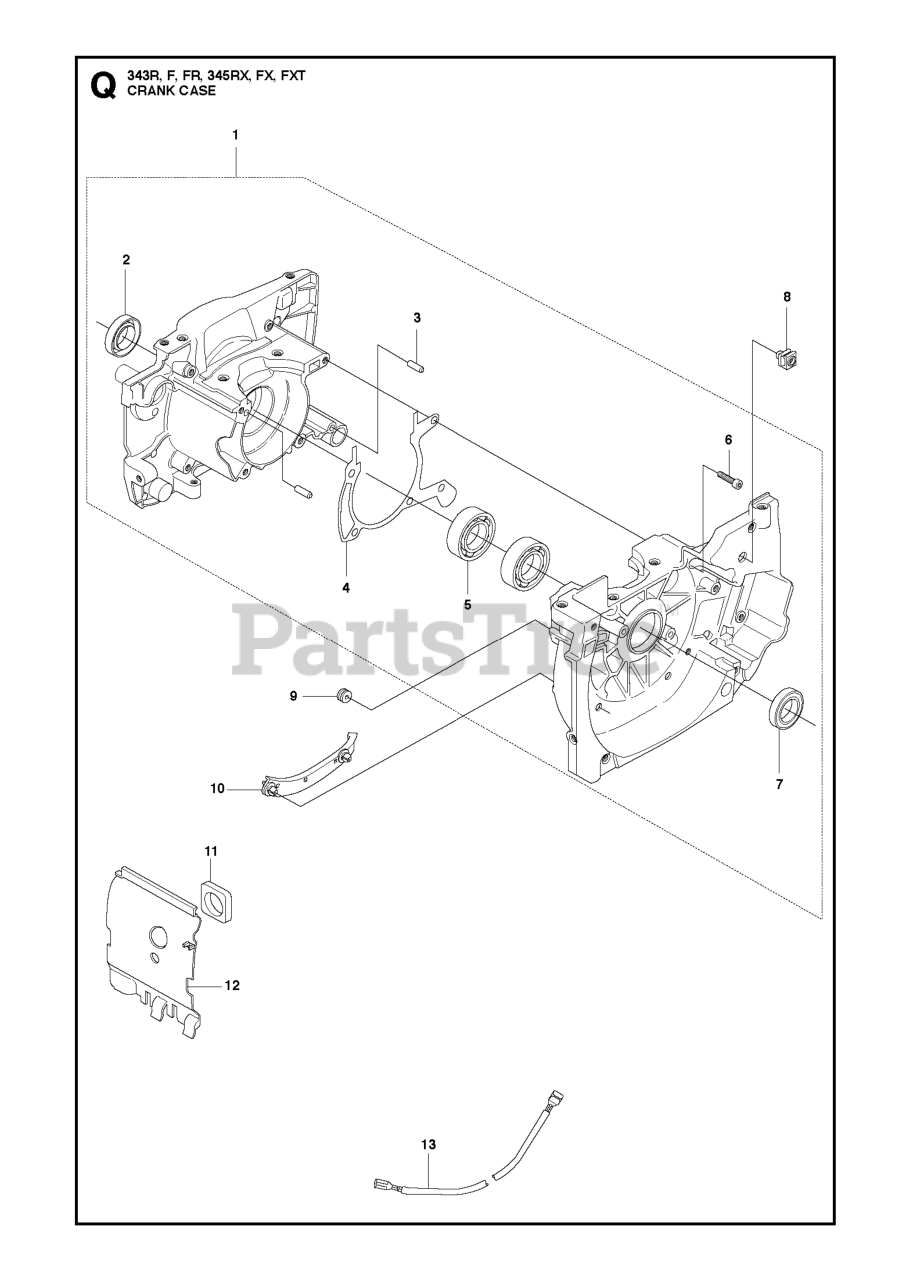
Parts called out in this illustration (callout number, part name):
2	SEALING RING
3	PIN 5X14
5	BALL BEARING
6	SCREW MC6S 5X20
8	CABLE SOCKET
9	FUEL TANK BUSHING
11	SEAL
12	AIR CONDUCTOR
13	SHORTING LEAD
